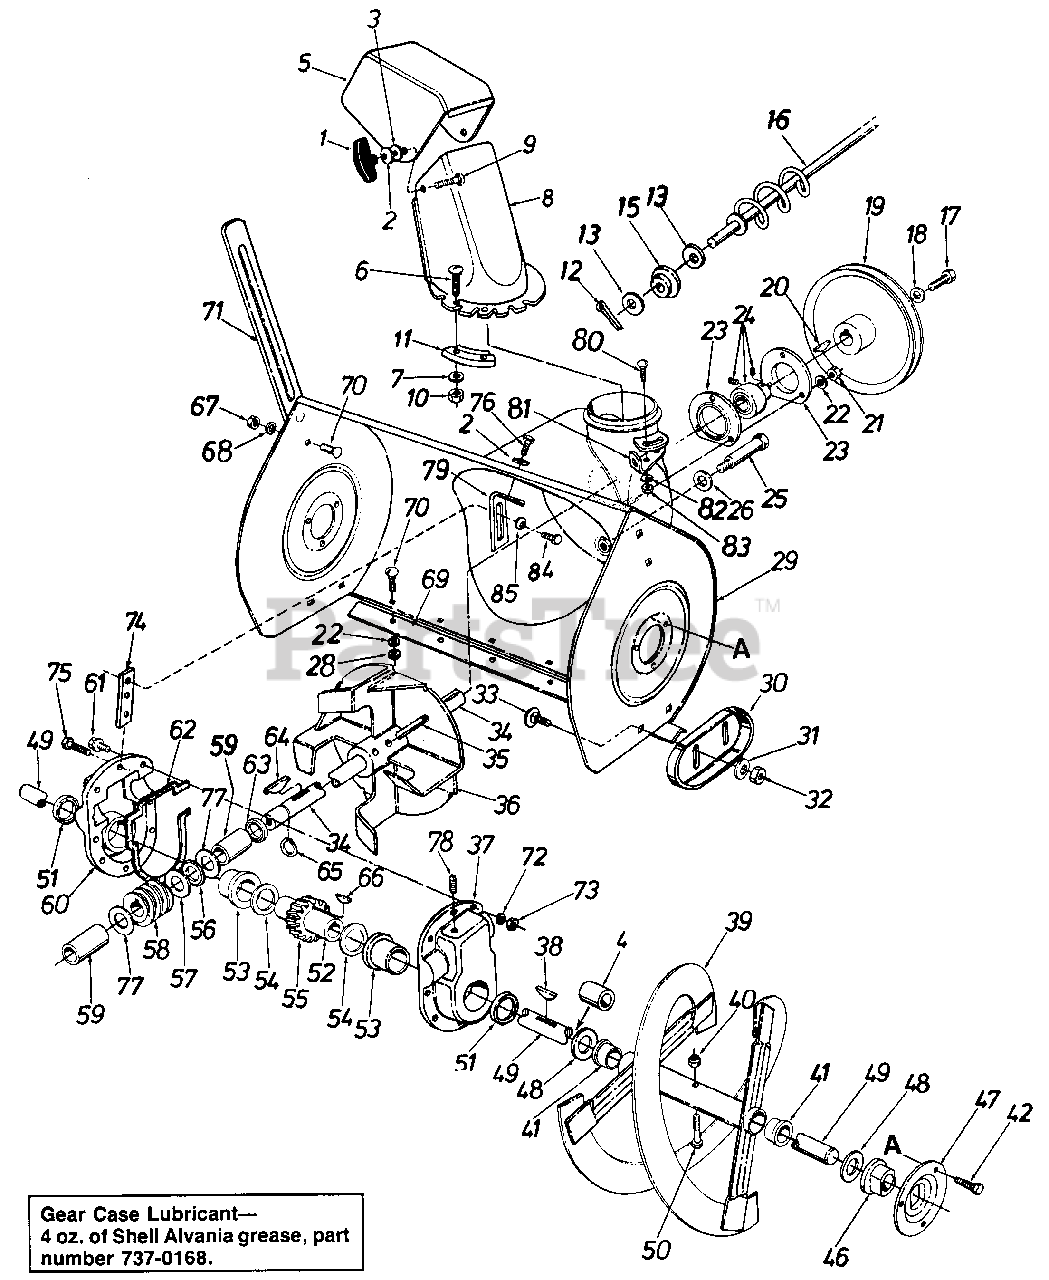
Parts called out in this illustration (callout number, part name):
1	KNOB-HANDLE ASSY
2	WASHER-BELL .337 X .867 X .057
3	WASHER-FL-.312 X 1.125 X .125
5	CHUTE-UPPER
6	SCREW-TRUSS MACH
7	WASHER-FL-.281 ID X .50 OD X .063
8	CHUTE-LOWER
9	BOLT-CARRIAGE 5/16-18 X 1.00
10	NUT-HEX CENTER L-1/4-20
11	KEEPER-CHUTE FLANGE
12	PIN-COTTER-3/32 DIA X .75
13	WASHER-FL-.385 ID X .62 OD X .063
15	BUSHING-.380 ID
16	CRANK ASSY-CHUTE
17	SCREW-HEX 5/16-18 X .88 SPECIAL
18	WASHER-BELL .337 X .867 X .057
19	PULLEY-V-1/2 ID X 10.0 OD
20	KEY-HI-PRO #9-3/16X3/4 DIA-HDN
21	NUT-HEX 5/16-18
22	WASHER-LOCK-5/16
23	HOUSING-BRG
24	BEARING-SELF ALIGN
25	STUD-3/8-16X2.75
26	WASHER-BELL .400 ID X .88 X .060
28	NUT-HEX 5/16-18
29	HOUSING ASSY-BLOWER
30	SLIDE SHOE
31	WASHER-BELL .400 ID X .88 X .060
32	NUT-HEX JAM 3/8-18
33	BOLT-CARRIAGE 3/8-16 X .62
34	AXLE-BLOWER
35	PIN-SPRING SPIR 5/16 X 1.75
38	KEY-WOODRUFF #91-1/4X3/4 DIA-HDN
42	SCREW-HEX HD TAP
46	BEARING-FLANGE
47	HOUSING-BRG
48	WASHER-FL
49	AXLE-SPRIAL
50	BOLT-HEX 5/16-18X1.75
51	SEAL-OIL
52	SHAFT-WORM GEAR
53	BEARING-FLANGE
54	WASHER-FL-1.50 X 2.25 X .030
55	GEAR-WORM-LH-DBL THD
56	BEARING-THRUST
57	WASHER-FL-881.D.X1.40 O.D.X.155
58	GEAR-WORM-LH-DBL THD
59	SLEEVE
60	HOUSING W/FL BRG-RH-GEAR
61	SCREW-HEX 5/16-18 X 1.00
62	GASKET-RUBBER
63	SEAL-OIL
64	KEY-HI-PRO #9-3/16X3/4 DIA-HDN
65	RING-SNAP FOR .875 SHAFT
66	KEY-WOODRUFF #91-1/4X3/4 DIA-HDN
67	NUT-HEX 5/16-18
68	WASHER-LOCK-5/16
70	BOLT-CARRIAGE 5/16-18 X .62
71	CUTTER-DRIFT
72	WASHER-SHAKE PROOF
73	NUT-HEX INS L-5/16-18
74	PLATE-SUPPORT-GEAR HSG
75	SCREW-HEX 5/16-18 X 1.25
76	SCREW-HEX HD TAP
77	WASHER-FL-881.D.X1.40 O.D.X.155
78	PLUG-VENTED-PLASTIC
80	BOLT-CARRIAGE 5/16-18 X .75
82	WASHER-BELL .337 X .867 X .057
83	NUT-HEX 5/16-18
84	SCREW-HEX 1/4-28 X .75
85	WASHER-SPRING BELL
